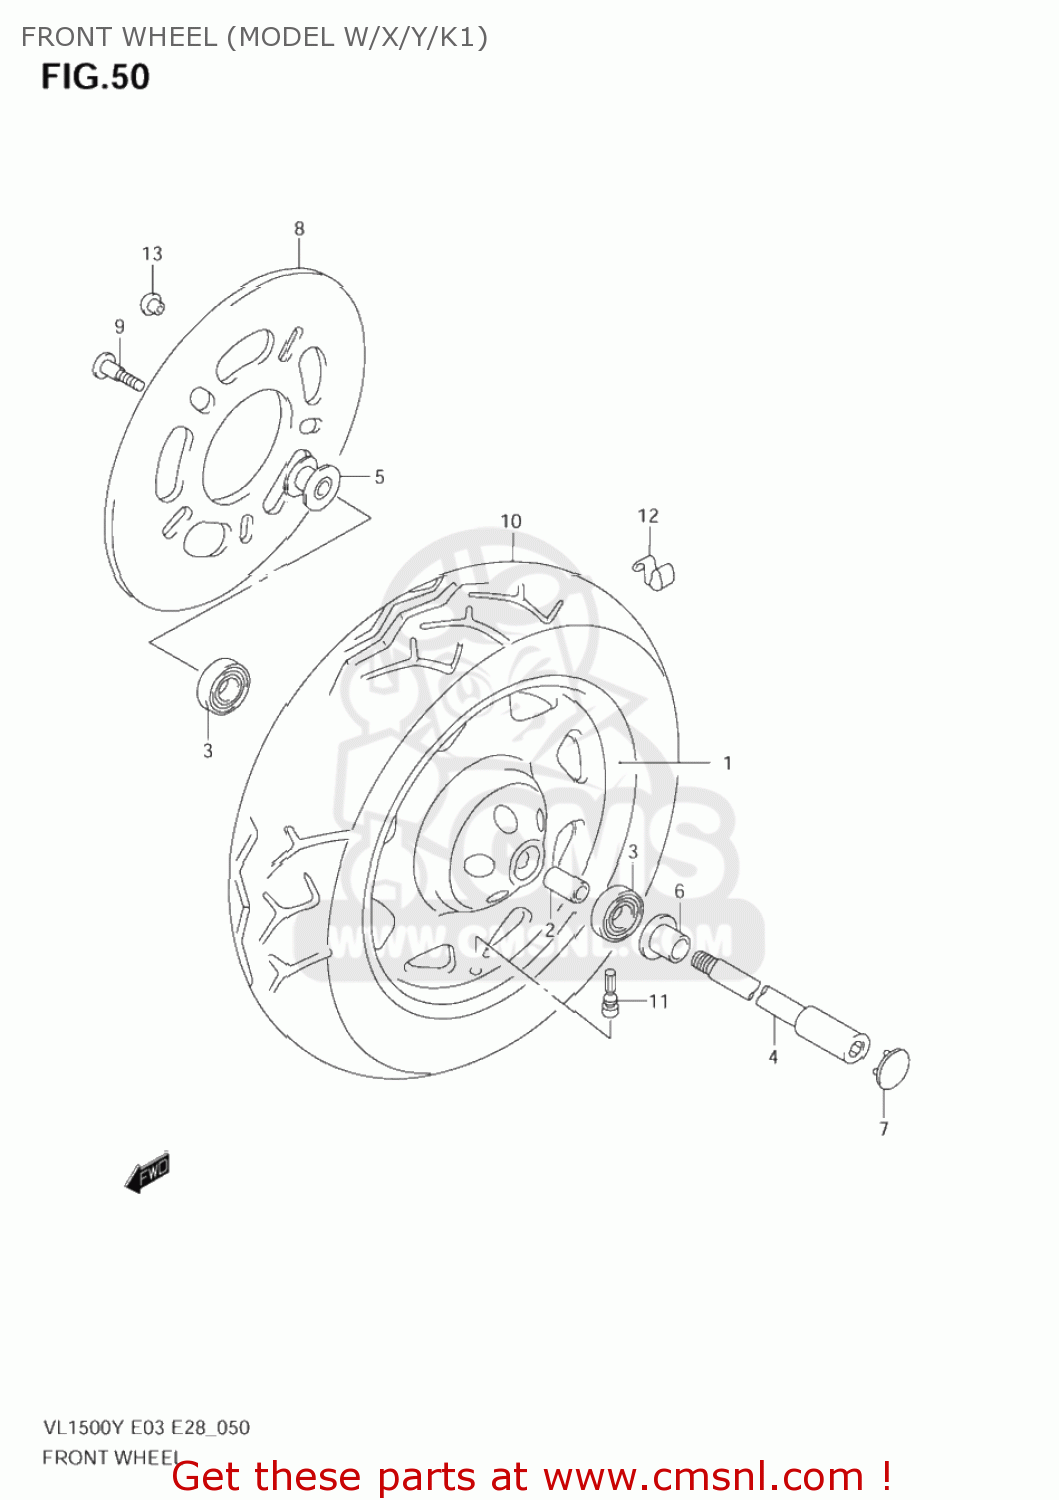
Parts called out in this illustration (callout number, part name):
1	WHEEL,FR(16XMT3.50)
2	SPACER,FR HUB BEARING
3	BEARING
4	AXLE,FR
5	SPACER,FR AXLE,R
6	SPACER,FR AXLE,R
7	CAP,FR AXLE
8	DISC,FR BRAKE
9	BOLT 8X33
10	TIRE,FRONT 150/80-16.7
11	VALVE ASSY,WHEEL RIM(TR412)
12	WEIGHT,BAL. 30
13	CAP,FR AXLE
